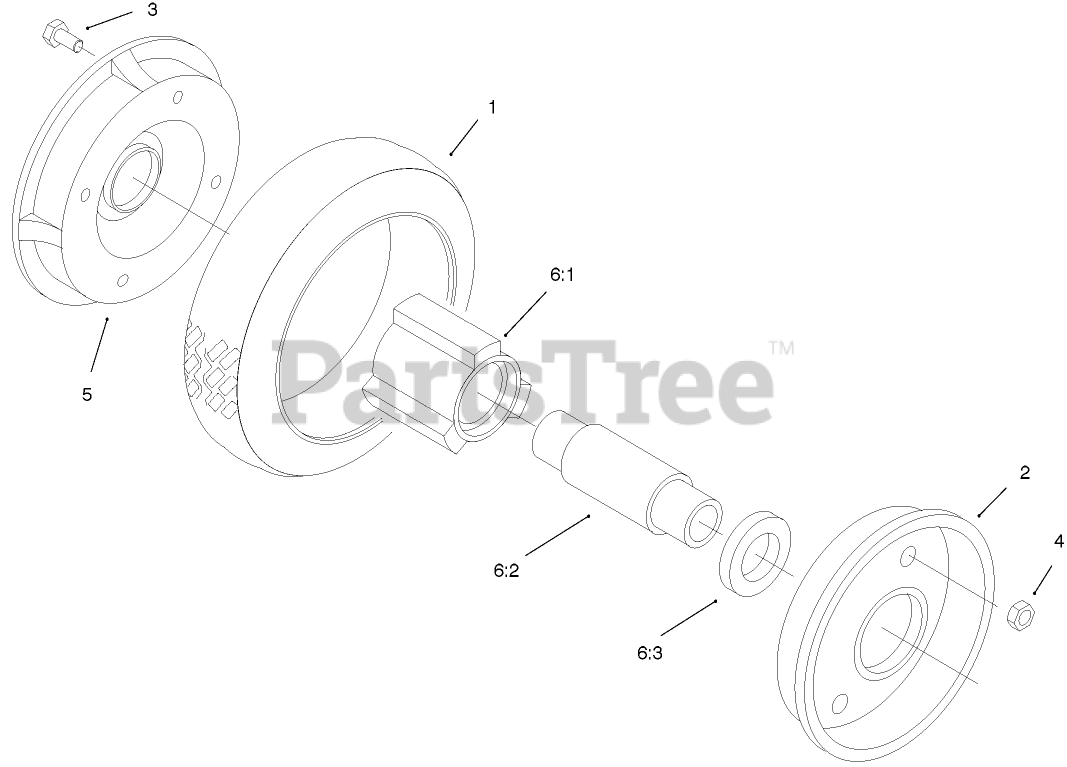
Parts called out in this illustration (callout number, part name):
3	SCREW-HH
4	NUT-LOCK, NI
6	Hub and Bearing ASM
6:1	HUB-BEARING
6:2	SPACER-BEARING
6:3	BEARING-WHEEL
